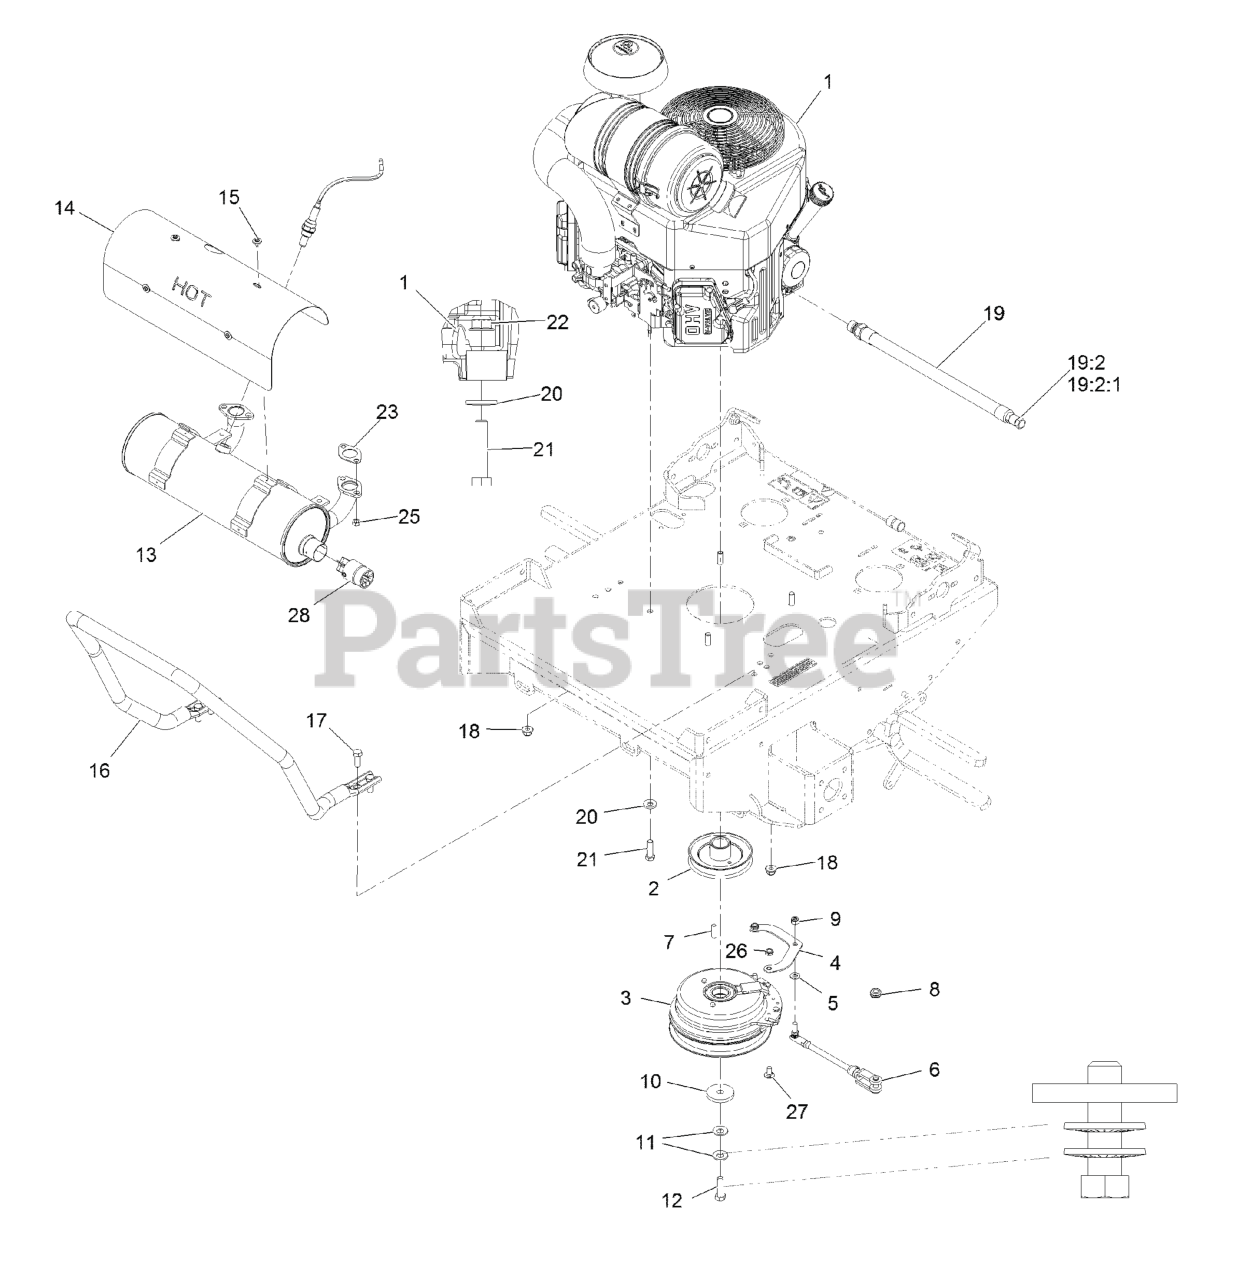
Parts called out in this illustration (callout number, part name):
2	SHEAVE W/ HUB
3	CLUTCH, 200 FT/LBS, 1.13
4	STRAP, CLUTCH
5	WASHER-PLAIN
6	ASM, CLUTCH ANCHOR
7	KEY
8	GROMMET
9	NUT-LOCK
10	WASHER-CLUTCH
11	WASHER-SPRING
12	BOLT-HEX, TAP
13	MUFFLER-TTX, EFI
14	SHIELD-MUFFLER,TTX EFI
15	SCREW-HH, THREAD FORMING
16	GUARD,AIR CLEANER
17	SCREW-HH
18	NUT-HF, NI
19	OIL DRAIN HOSE ASM
19:2	PLUG-HH
19:2:1	O-RING
20	WASHER-SPRING
21	SCREW-HH
22	NUT-HF, NI
23	GASKET-EXHAUST
25	NUT-FLANGE
26	NUT-LOCK, NI
27	SCREW-CARR
28	ARRESTOR,SPARK 1.375 DIA
